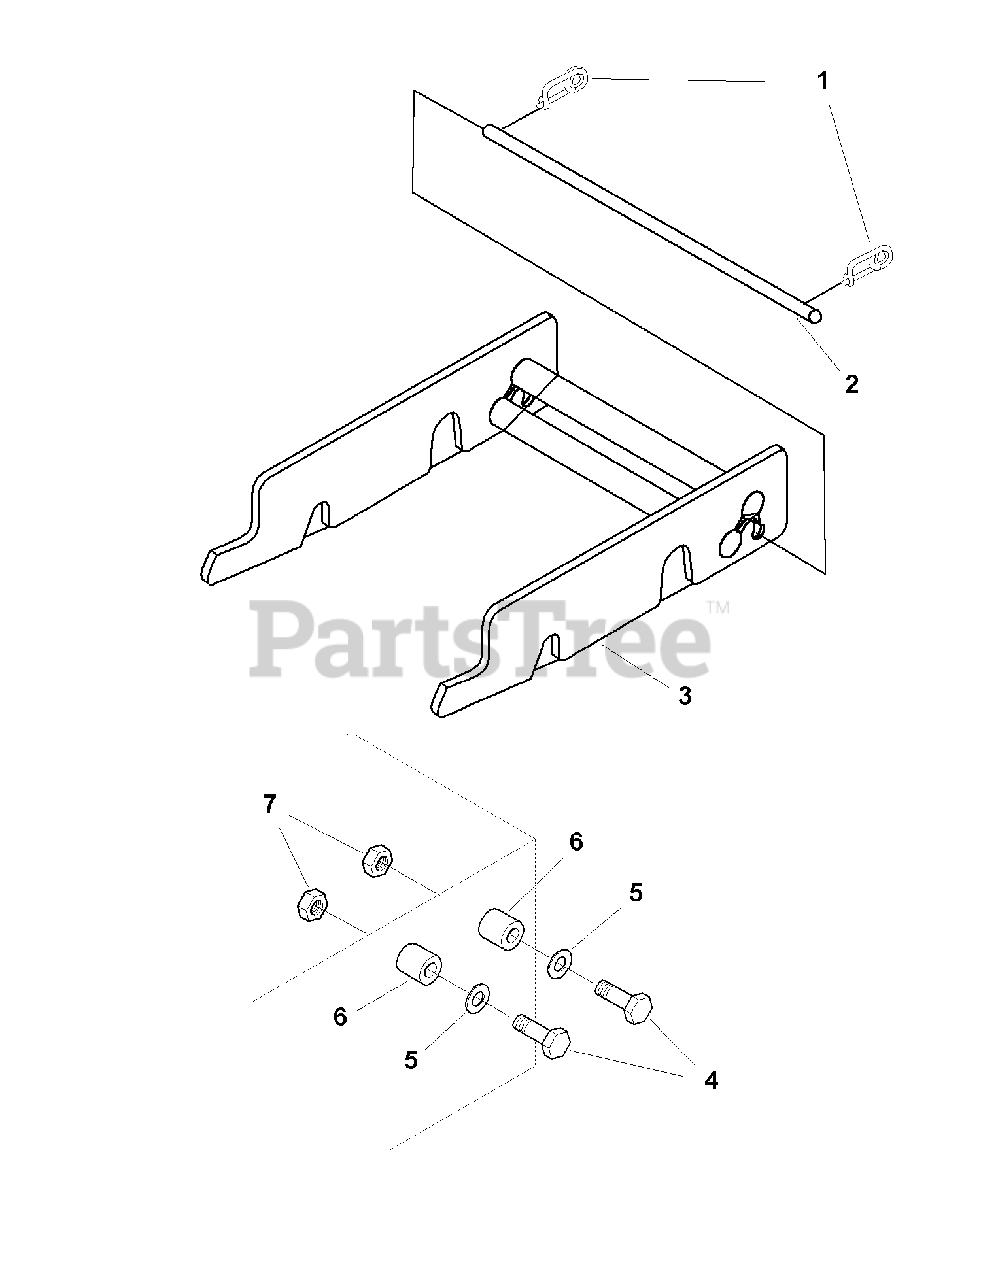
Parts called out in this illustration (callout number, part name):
1	CLIP, Safety Pin
3	HITCH ASSEMBLY
4	CAPSCREW, Hex Head, 1/2-13 x 2-1/2
5	WASHER
7	NUT, ESNA, Lock 1/2-13
